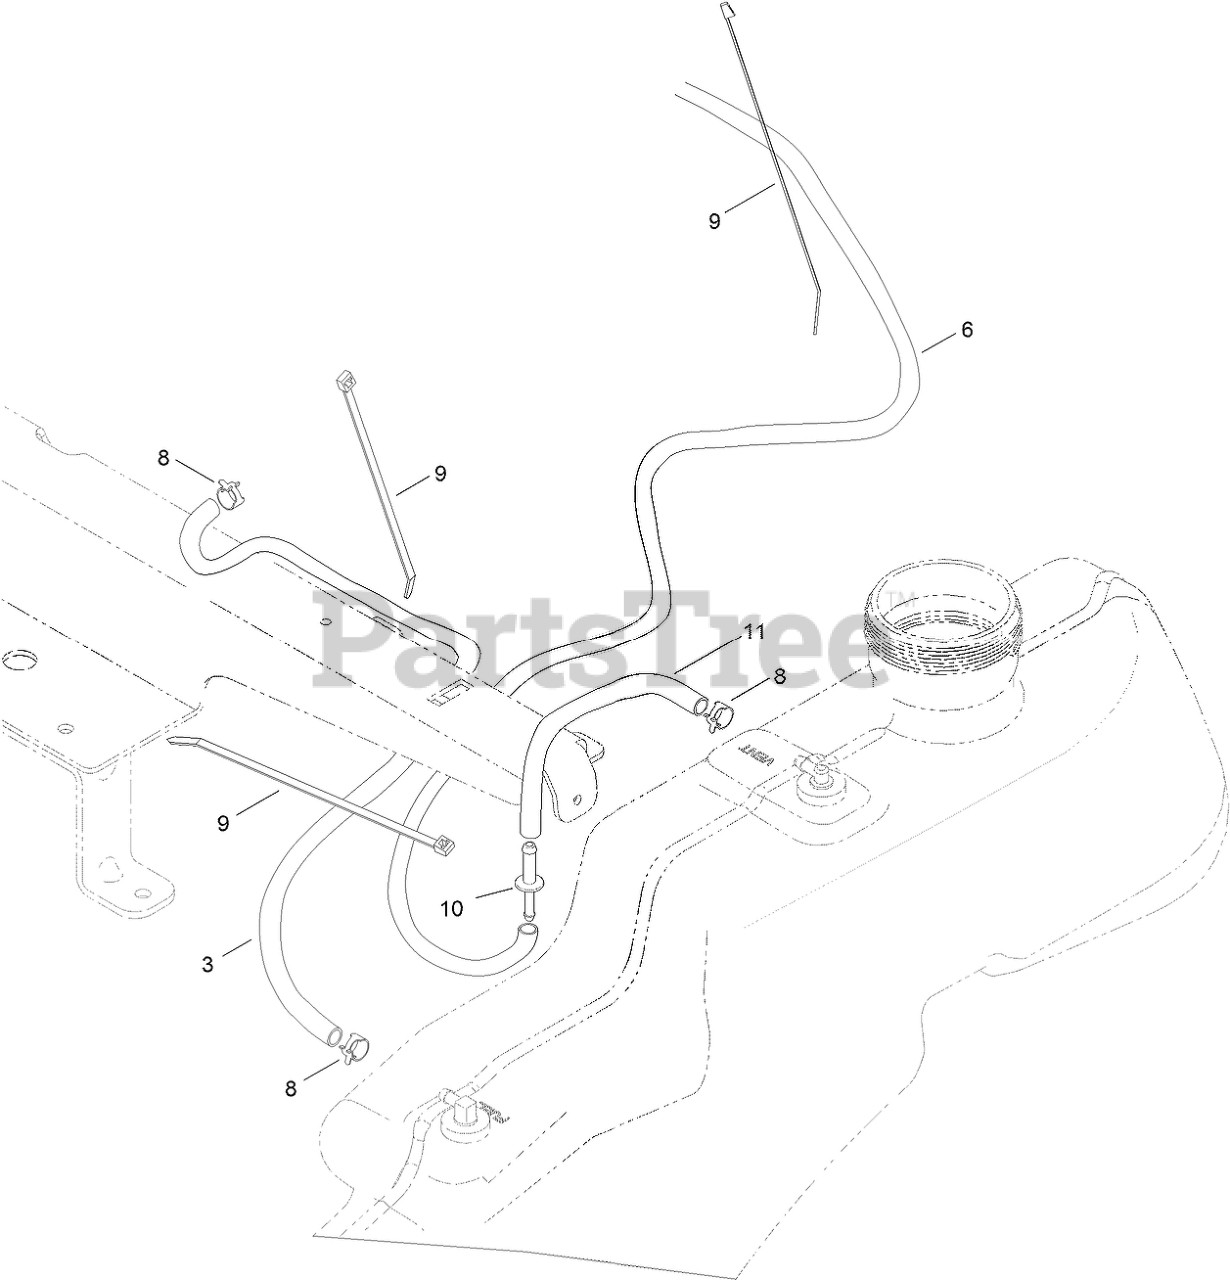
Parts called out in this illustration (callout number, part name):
3	HOSE-FUEL
6	HOSE-FUEL
8	CLAMP-HOSE
9	TIE-CABLE
10	ADAPTOR-ORIFICE
11	HOSE-FUEL
